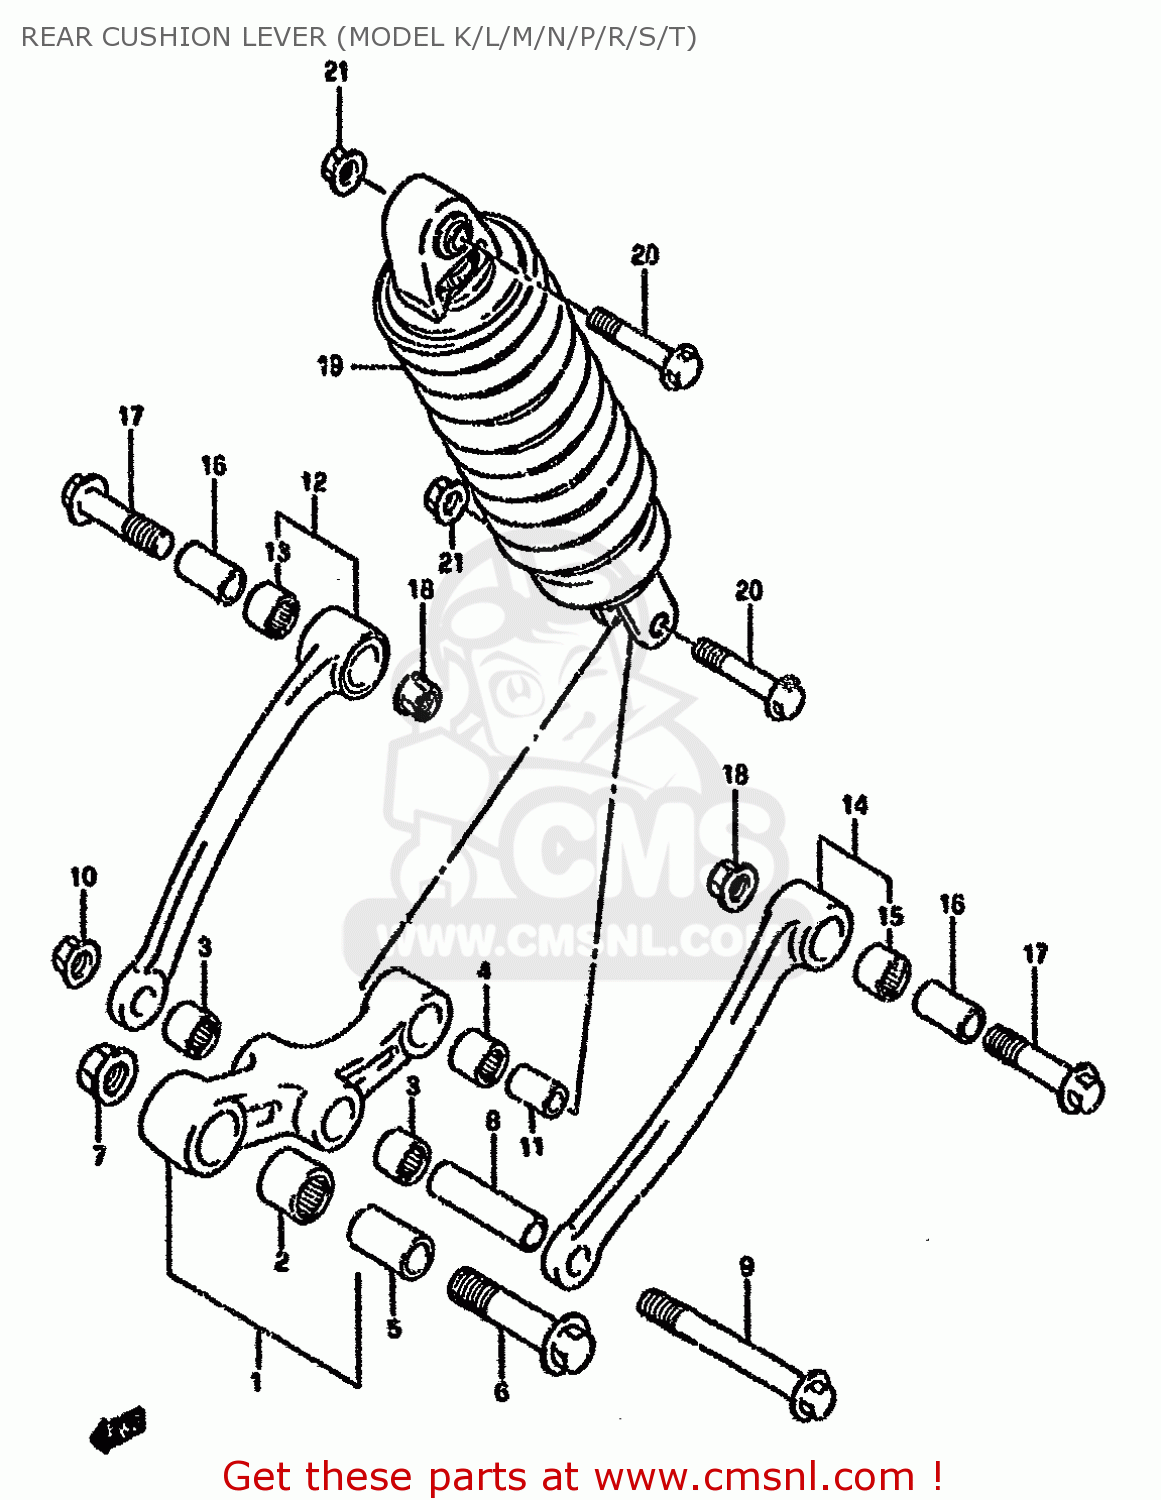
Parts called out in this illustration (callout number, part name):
1	LEVER SET,RR CUSHION
2	BEARING(20X27X30)
3	BEARING(17X24X25)
4	BEARING(17X24X26)
5	SPACER(14X20X34)
6	BOLT(14X62)
7	NUT 14MM
8	SPACER(12X17X60)
9	BOLT(12X96)
10	NUT 12MM
11	SPACER,RR CUSHION LEVER
12	ROD SET,RR CUSHION,R
13	BEARING(17X24X26)
14	ROD SET,RR CUSHION,L
15	BEARING(17X24X26)
16	SPACER(12X17X29)
17	BOLT L:52
18	NUT 12MM
19	ABSORBER ASSY,RR SHOCK
20	BOLT(10X52)
21	NUT 10MM
